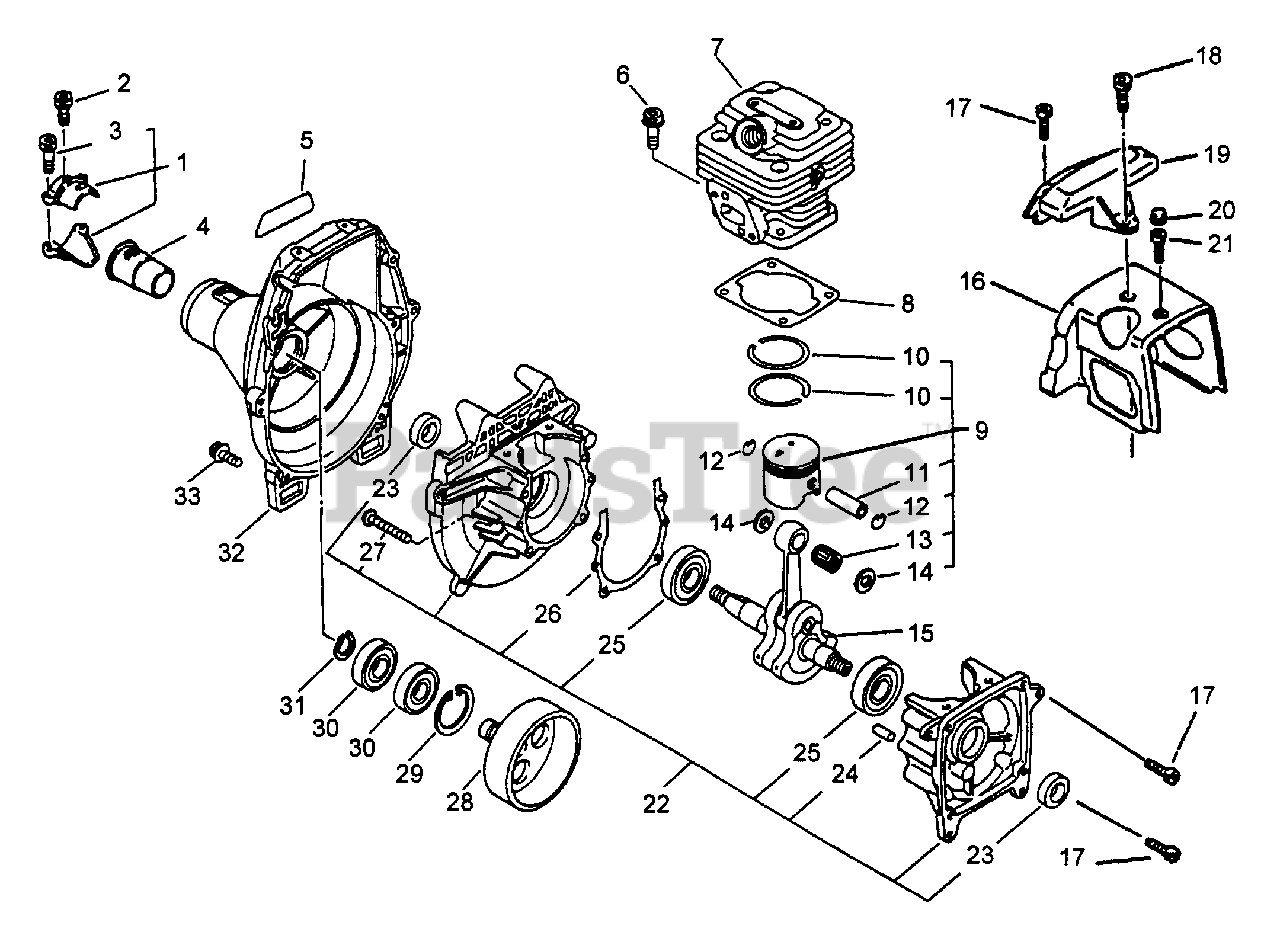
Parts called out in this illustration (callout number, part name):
1	HOLDER KIT
2	SCREW - 5X12
3	SCREW - 5X25
5	LABEL - ECHO
6	SCREW - 5X20
7	CYLINDER
8	GASKET, CYLINDER
9	PISTON KIT
10	RING, PISTON
11	PIN, PISTON
12	RING, RETAINING
13	BEARING, NEEDLE
14	SPACER, PISTON
15	CRANKSHAFT ASSY
16	COVER, ENGINE
17	SCREW - 4X14
18	SCREW - 5X16
19	GUARD - TOP
21	SCREW - 5X12
22	CRANKCASE KIT
23	SEAL, OIL
24	PIN - LOCATING
25	BEARING, BALL - 6201
26	GASKET, CRANKCASE
27	SCREW - 5X30
28	DRUM, CLUTCH
29	RING, RETAINING - 28
30	BEARING, BALL - 6001
31	RING, RETAINING - 12
32	CASE, FAN
33	SCREW - 5X20
